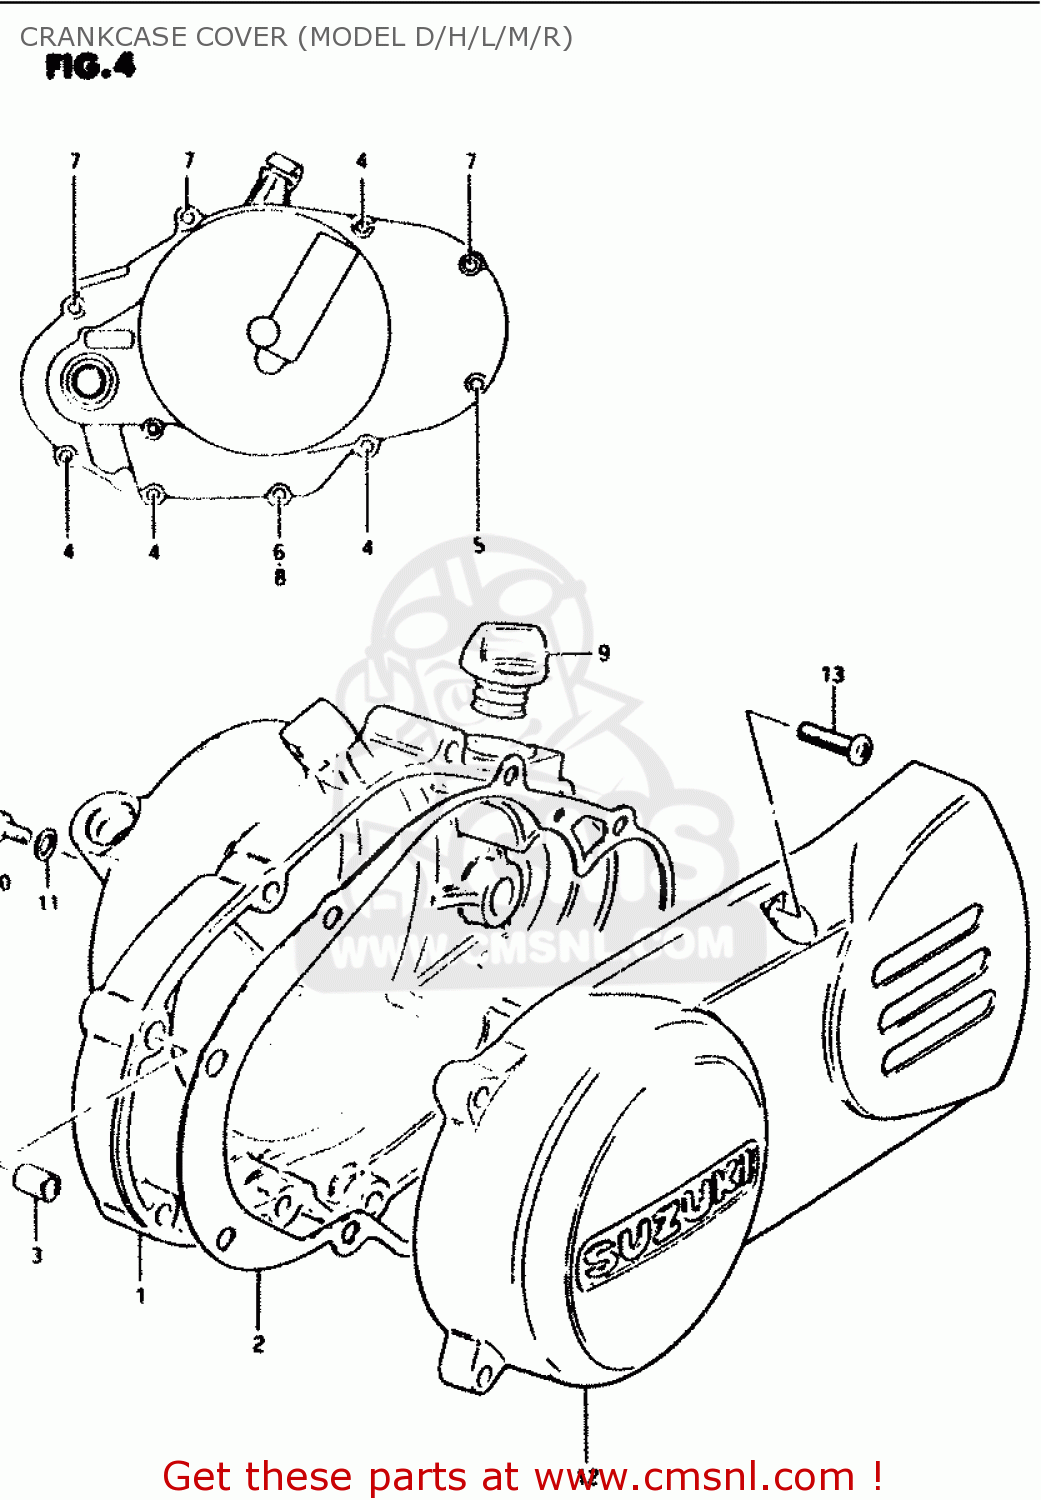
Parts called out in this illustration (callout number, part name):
1	COVER,CLUTCH
2	GASKET,CLUTCH COVER (NAS)
3	PIN
4	SCREW
5	SCREW
6	SCREW
7	SCREW
8	GASKET(6.2X11X1).2 (NAS)
9	PLUG
10	SCREW(6X10)
11	GASKET(6.2X11X1) (NAS)
12	COVER,MAGNETO
13	SCREW
